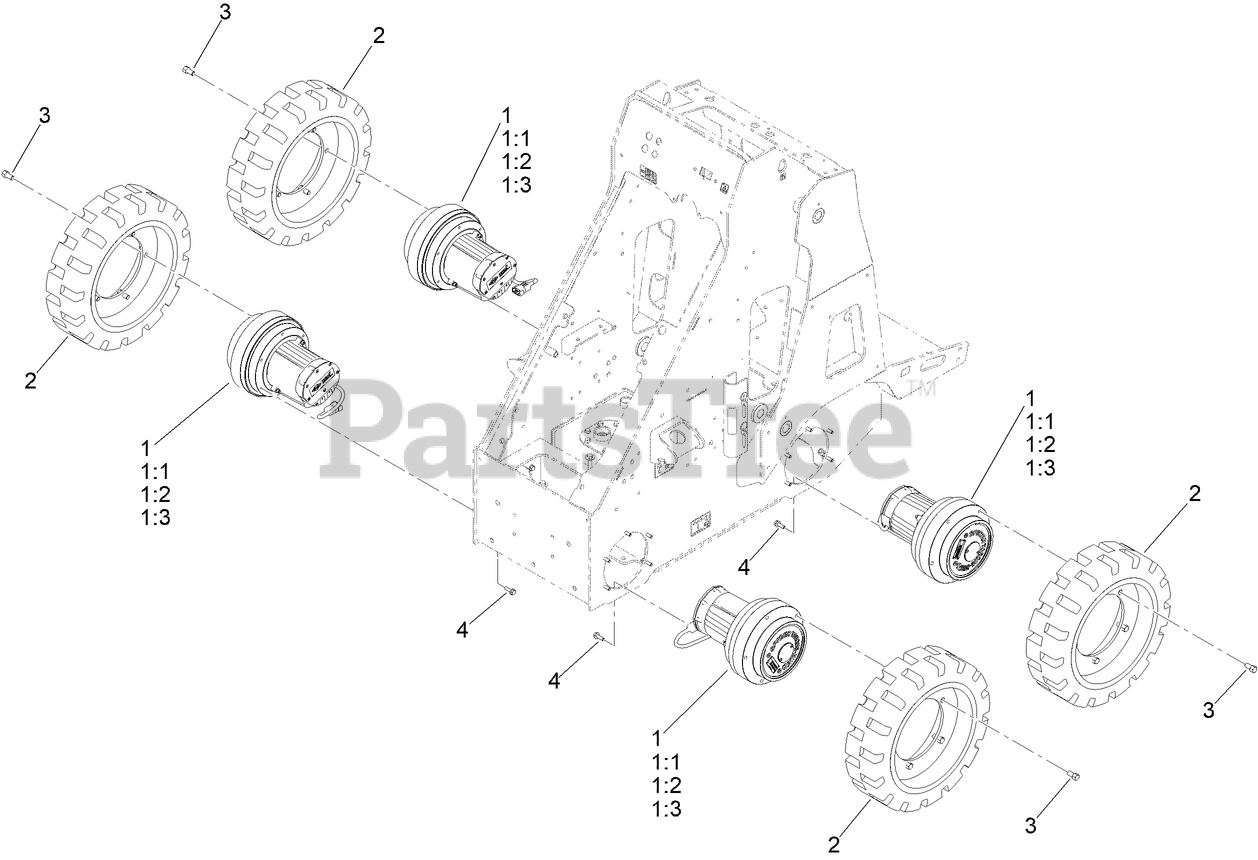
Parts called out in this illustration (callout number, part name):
1	MOTOR/GEN TORQUEHUB ASM-3KW 45:1 RDCTN
1:2	GEARBOX,PLNTRY-45:1 RDCTN
1:3	BRAKE,PARKING-TORQUEHUB
2	TIRE-SOLID
3	SCREW-HH, LUG M12 X 1.50
4	SCREW-HHF
